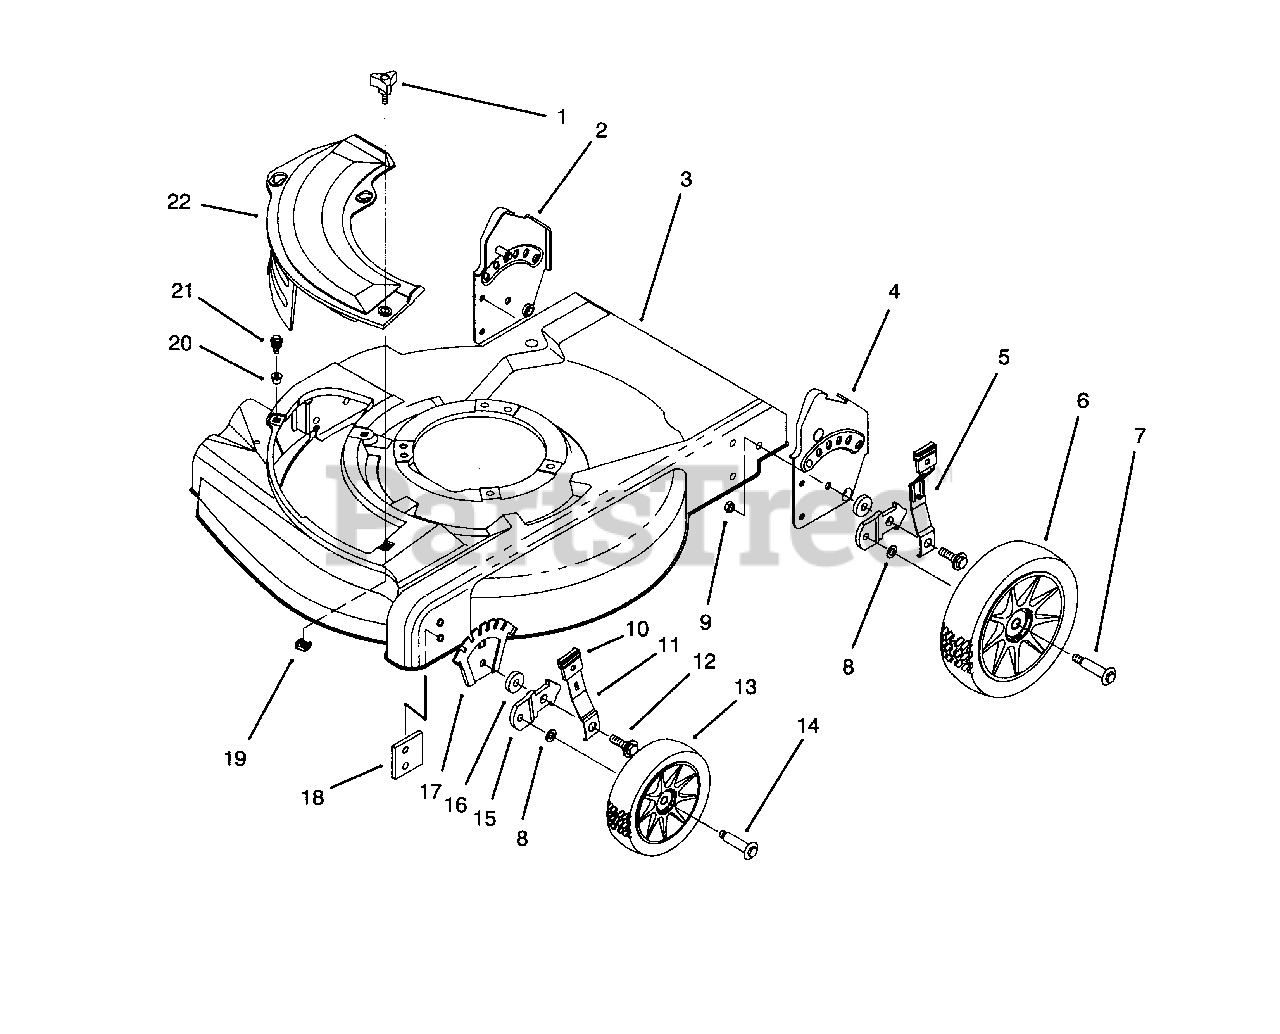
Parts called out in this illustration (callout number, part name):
1	Knob Cover Plate
2	Bracket-Handle R.H.
3	Housing
4	Bracket-Handle L.H.
5	Spring Arm Assembly
6	Wheel & Tire Assembly-8"
7	Bolt-Shoulder
9	Nut-Lock
10	Knob-Height Adjust
11	Spring Arm Assembly
12	Bolt-Shoulder
13	Wheel & Tire Assembly
14	Bolt-Shoulder
15	Bracket-Wheel Height Adj.
17	Plate-Height Adjust
18	Plate-Baffle
19	Nut-Cage
20	Grommet-Plastic
21	Screw-Sems Thr'd Form.
22	Plate-21" Mulch
